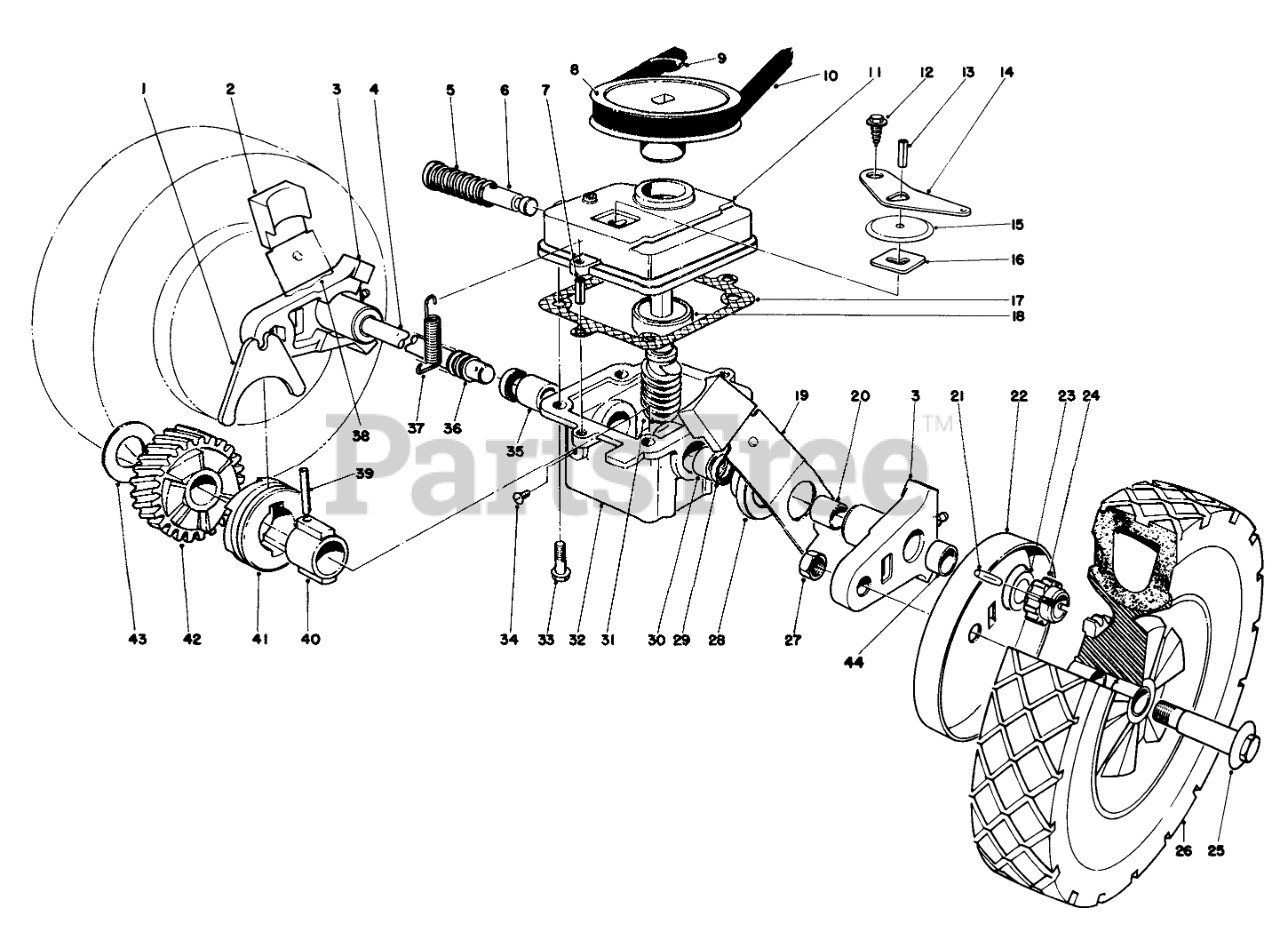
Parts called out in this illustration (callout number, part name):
1	SHIFTER FORK
2	KNOB-ARM
3	Pivot Arm (Incl. Ref. #20 & 44)
4	DRIVE SHAFT (SERVCE)
5	SPRING
6	Shift Rod
7	3/16 X 1/2 ROLL PIN
8	PULLEY
9	PUSH-ON 93-3236
10	V BELT
11	Case-Upper
12	Screw
13	PIN-ROLL
14	SHIFTER ARM
15	TRANS DUST COVER
16	LATCH PLATE
17	GASKET
18	Bearing
19	SPRING ARM ASM SP LH
20	BUSHING
21	Pin
22	WHEEL COVER
23	WASHER-THRUST
24	Pinion
25	BOLT-WHEEL
26	Wheel & Tire Assembly
27	Nut
28	End Cap
29	Seal
30	Bushing
31	Worm Shaft & Gear (Incl. Ref. #42)
32	Gear Case (Incl. Ref. #29-30 & 35)
33	Screw
34	NYLON SCREW
35	Bushing
36	COVER-SHAFT, DRIVE
37	TENSION SPRING
38	SPRING ARM ASM SP RH
39	COIL PIN
40	SLEEVE
41	CLUTCH JAW
42	Helical Gear
43	THRUST WASHER
44	BUSHING
